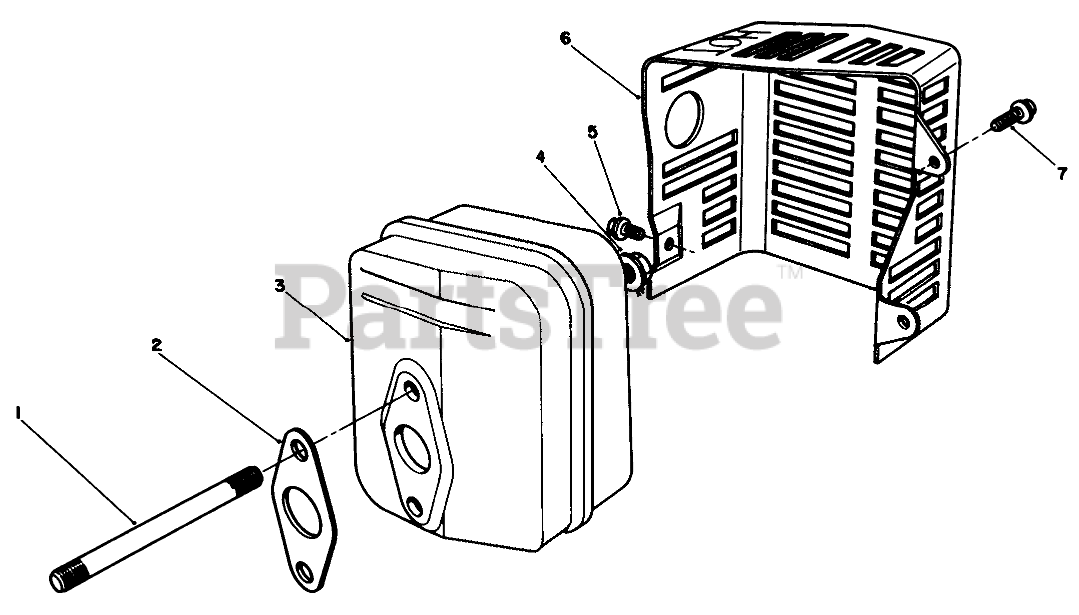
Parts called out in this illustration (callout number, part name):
1	HANDLE
2	SCREW-HHF
3	LOGO PLATE - RECOIL
5	SPRING
10	WASHER
18	SHROUD
